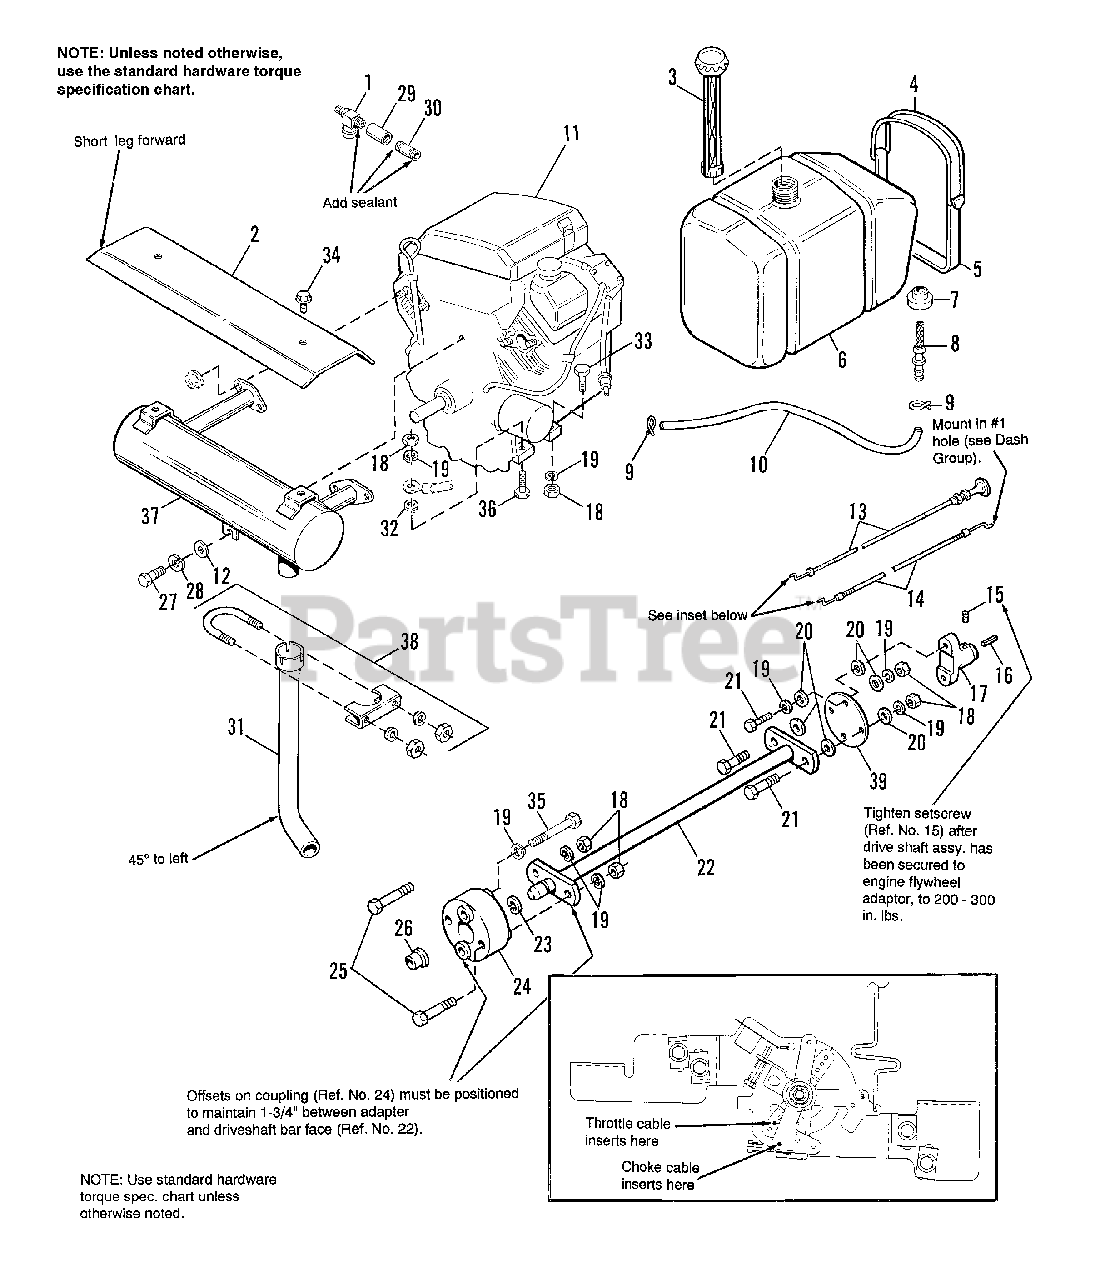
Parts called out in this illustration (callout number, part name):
1	SHUT OFF VALVE
2	HEAT SHIELD ASSEMBLY
3	CAP, Fuel Tank
4	STRAP, Fuel Tank
5	STRAP, Tank
6	TANK ASSEMBLY, Fuel
9	CLAMP, Hose
10	HOSE, Fuel, 15"
11	ENGINE, Kohler, 18 HP
12	WASHER, 15/32
13	CHOKE CONTROL
14	THROTTLE CONTROL
15	SETSCREW, 3/8-24 x 3/8
16	KEY, Drive Shaft, 3/16 x 1-1/4
17	FLANGE, Drive Shaft
18	NUT, Hex, Full, 3/8-16
19	LOCKWASHER, 3/8
20	WASHER
21	CAPSCREW, Hex Hd, 3/8-16 x 1-1/4
22	SHAFT ASSEMBLY, Drive
23	RETAINING RING
24	COUPLING, Compression
25	CAPSCREW, Hex Hd, 3/8-16 x 2-1/2
27	CAPSCREW, Hex Hd, 7/16-14 x 1
28	LOCKWASHER, 7/16
29	COUPLING, Pipe, Straight
30	NIPPLE, Pipe, 3/8 x 1
31	PIPE, Exhaust,Elbow
32	WASHER, External Tooth, 3/8
33	CAPSCREW, Hex Hd, 3/8-16 x 1-3/4
34	CAPSCREW, Hex Hd, Taptite, 5/16-18 x 1/2
35	CAPSCREW, Hex Hd, 3/8-16 x 1-1/4
36	CAPSCREW, Hex Head, M8-1-1/4 20mm
37	MUFFLER, Exhaust
38	CLAMP, Exhaust
